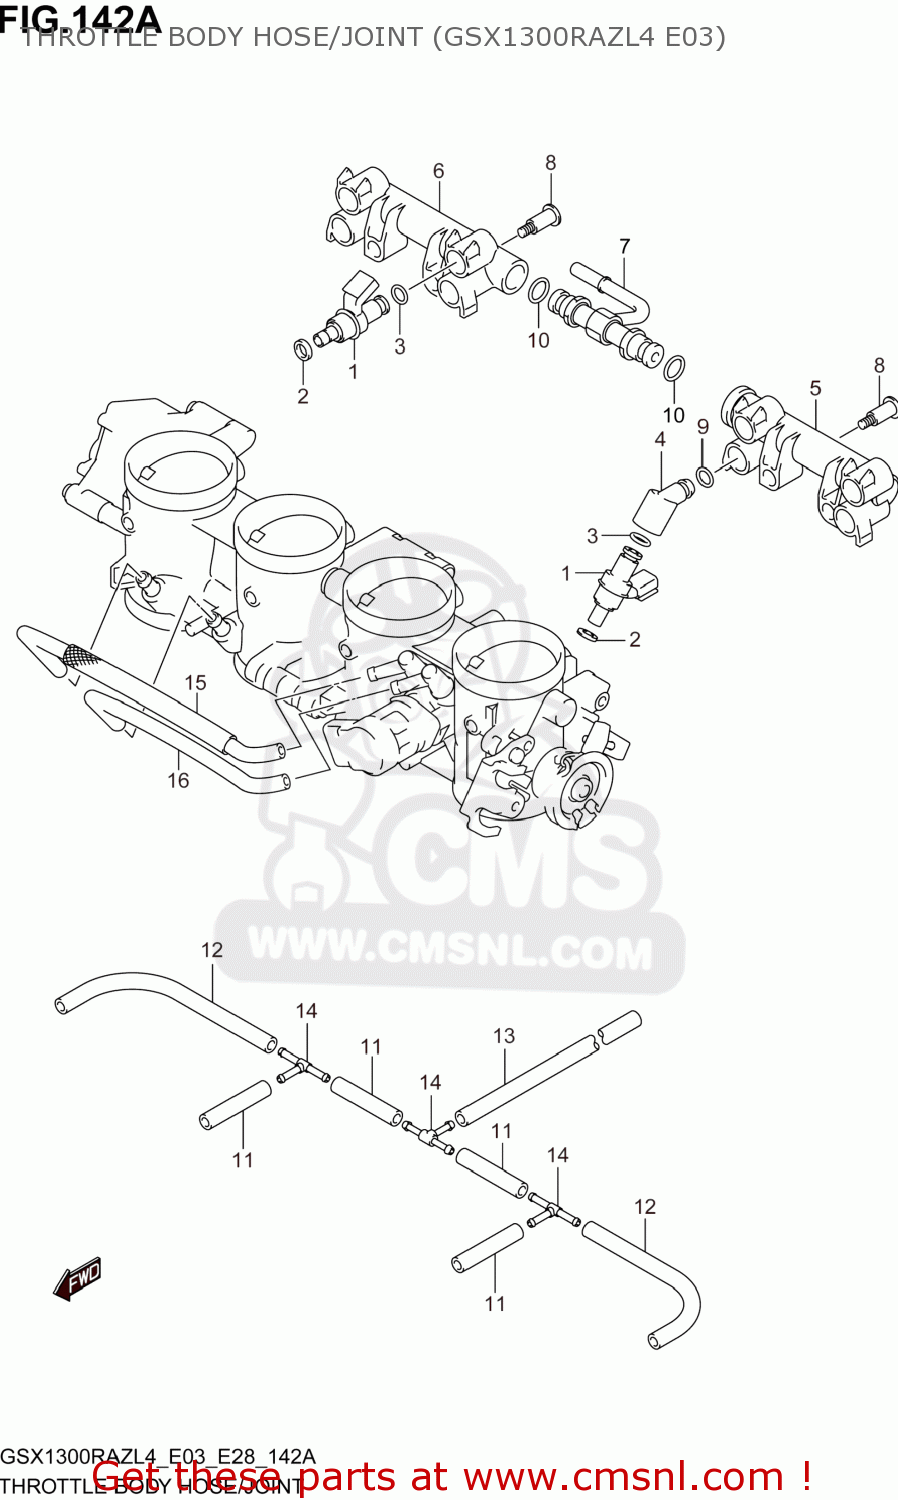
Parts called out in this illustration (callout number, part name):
1	INJECTOR ASSY
2	RING,SEAL
3	O RING
4	PIPE,FUEL
5	PIPE,FUEL
6	PIPE,FUEL
7	JOINT
8	SCREW
9	O RING
10	O RING
11	HOSE,RUBBER(L:35)
12	HOSE,RUBBER(L:100)
13	HOSE,RUBBER(3X7X170)
14	JOINT
15	TUBE
16	TUBE
